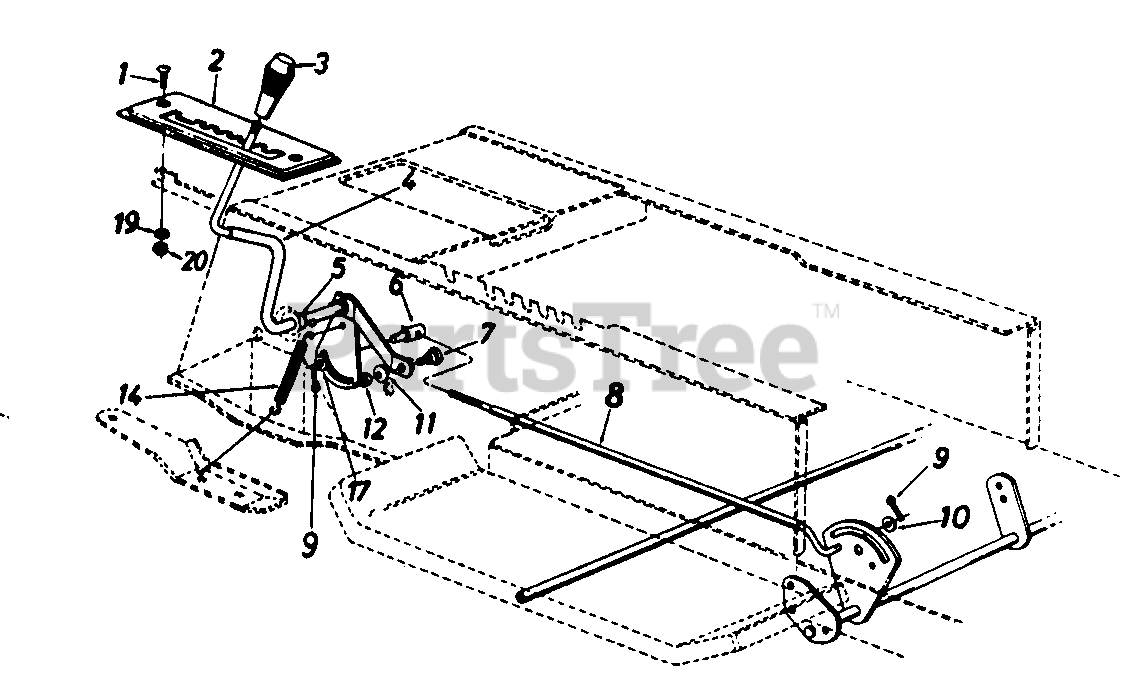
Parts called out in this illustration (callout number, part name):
1	Truss Mach. Scr. 1/4-20 x .75" Lg.
4	Speed Selector Cam Ass'y.
5	Flat Washer .53" I.D. x .93"
6	Ferrule 3/8-24 x .37" Dia.
7	Shoulder Bolt
8	Speed Control Link
9	Cotter Pin 3/32" Dia. x 1.0"
10	Fl-Wash. .469" I.D. x .88"
11	L-Wash. 5/16" I.D.*
12	Hex Nut 5/16-18 Thd.
14	Spring .38" O.D. x 3.18" Lg.
17	Fl-Wash. .385" I.D. x .62"
19	L-Wash. 1/4" I.D.
20	Hex Nut 1/4-20 Thd.
